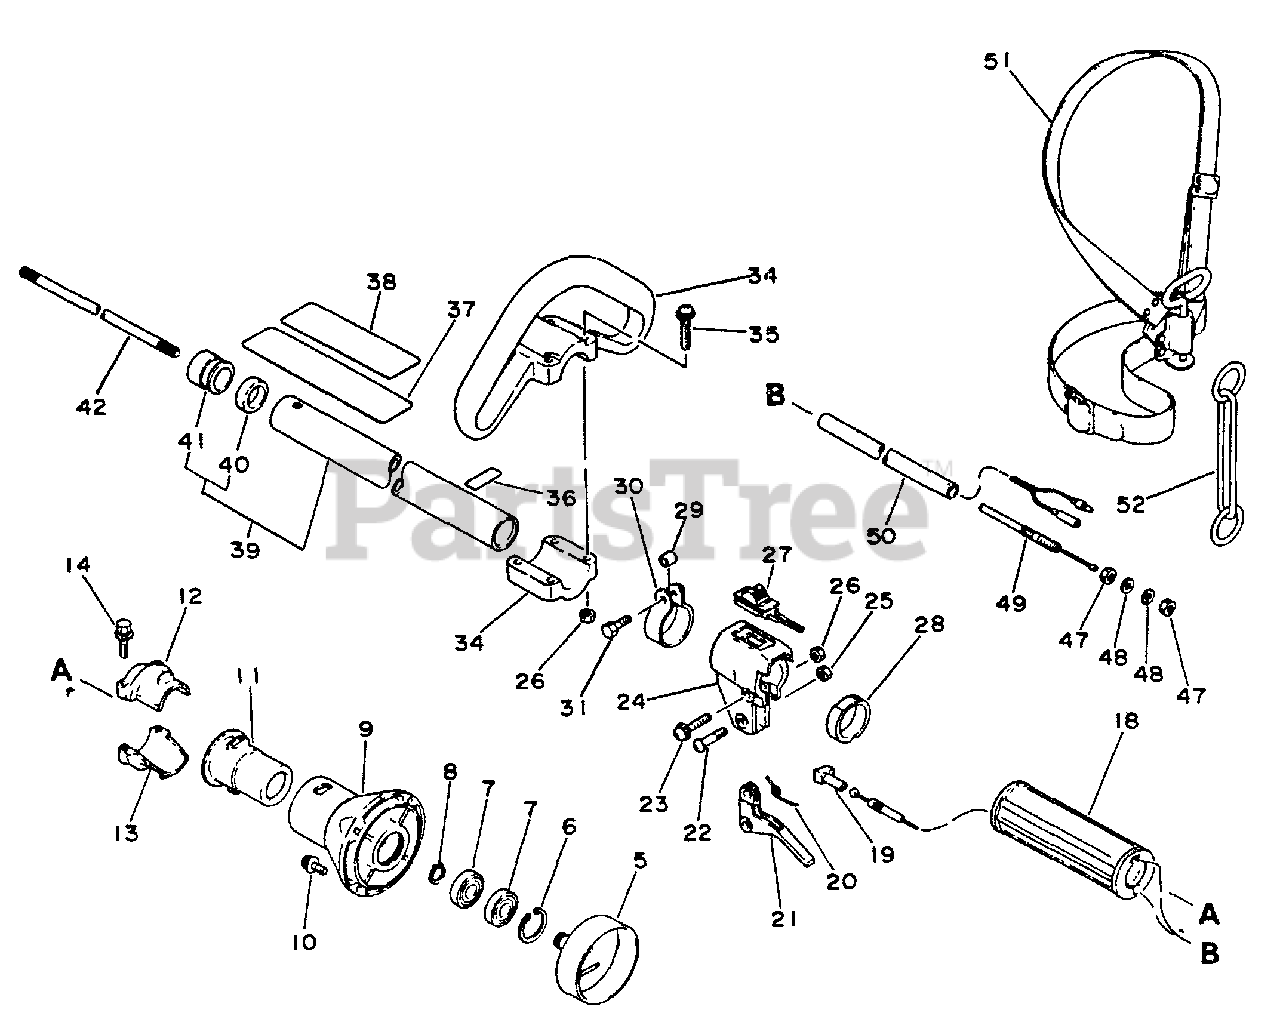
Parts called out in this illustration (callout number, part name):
5	DRUM, CLUTCH
6	RING, SNAP 28
7	BEARING, BALL 6001
8	RING, RETAINING - 12
9	CASE, CLUTCH
10	SCREW 5×16
12	HOLDER
13	HOLDER
14	BOLT - 5×25
18	GRIP
19	GUIDE, CABLE
20	SPRING, THROTTLE
21	TRIGGER, THROTTLE
23	SCREW 5×30
24	BRACKET, THROTTLE
25	LOCKNUT - 5
26	NUT M5
27	IGNITION SWITCH ASSY
29	SPACER, GUARD
31	BOLT 5×18
34	LOOP HANDLE ASSY
35	SCREW 5×35
36	LABEL - ALIGNMENT
37	LABEL - CAUTION
39	MAIN PIPE ASSY
42	DRIVESHAFT
48	WASHER 6.5×11.5×0.8
49	CABLE, THROTTLE
51	SHOULDER STRAP ASSY
52	HOOK
